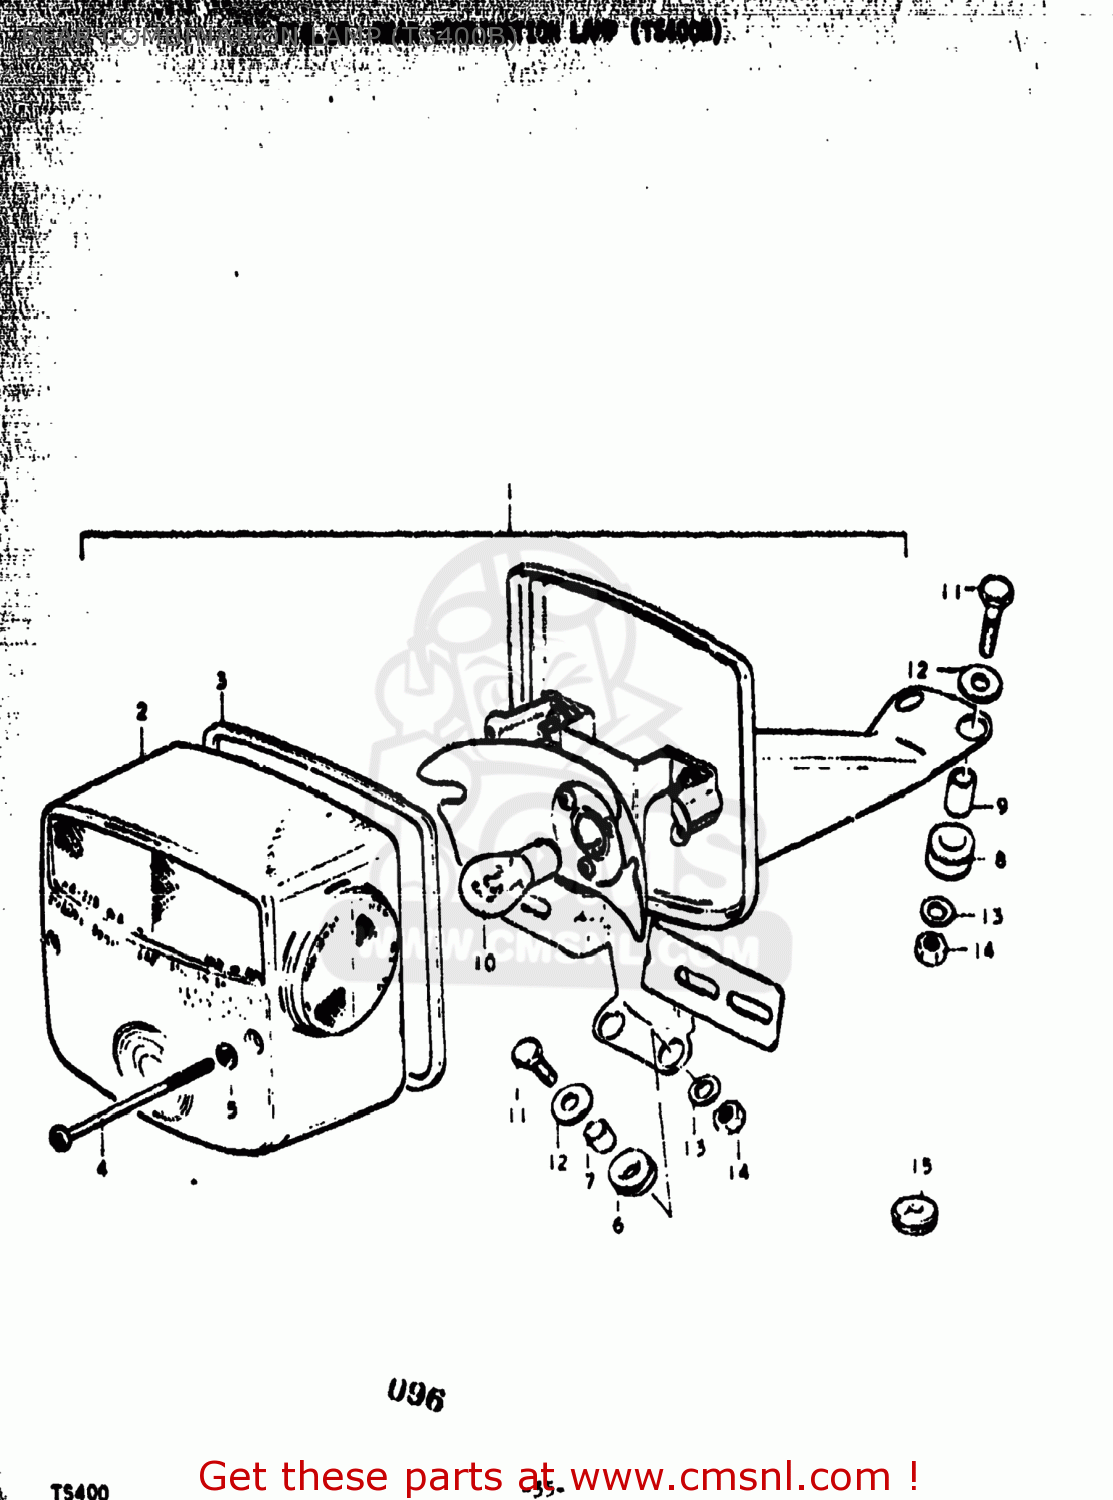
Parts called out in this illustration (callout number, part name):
1	LAMP ASSEMBLY,REAR COMBINATION
2	LENS,REAR COMBINATION LAMP
3	GASKET (NAS)
4	SCREW
5	GASKET (NAS)
6	CUSHION
7	SPACER,REAR COMBINATION LAMP
8	CUSHION
9	SPACER,REAR COMBINATION LAMP
10	BULB(6V32/3CP,STANLEY)
11	BOLT
12	WASHER (6.5X20X1.2)
13	WASHER
14	NUT
15	GROMMET
